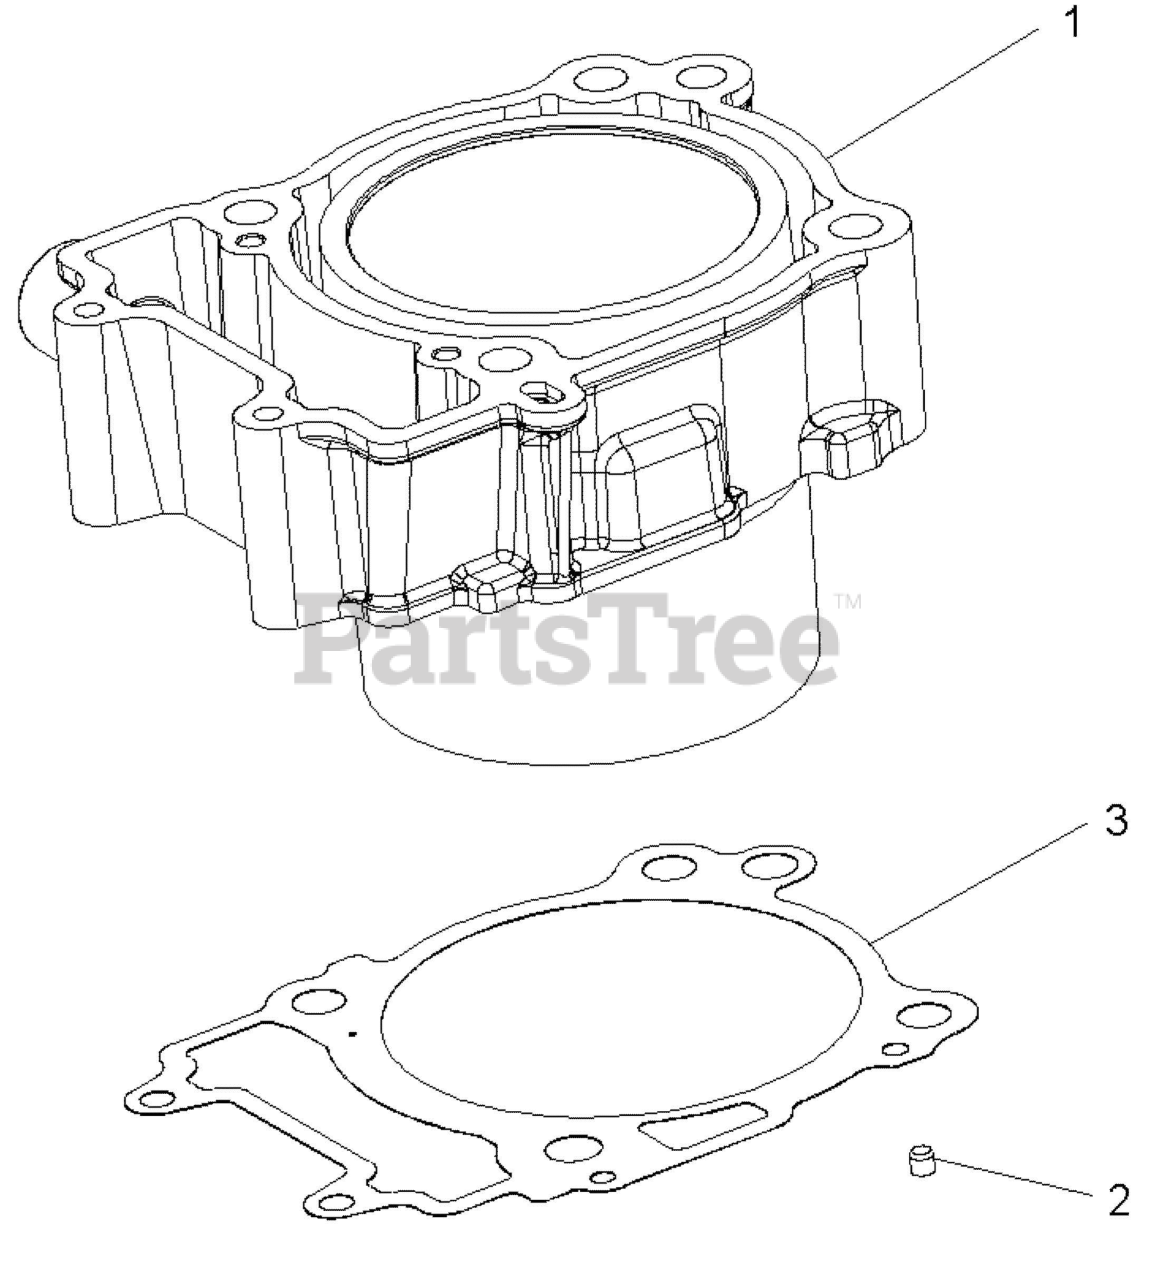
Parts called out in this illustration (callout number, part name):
1	ASM-CYLINDER,99MM
2	PIN-DOWEL,M6X10
3	GASKET-BASE
